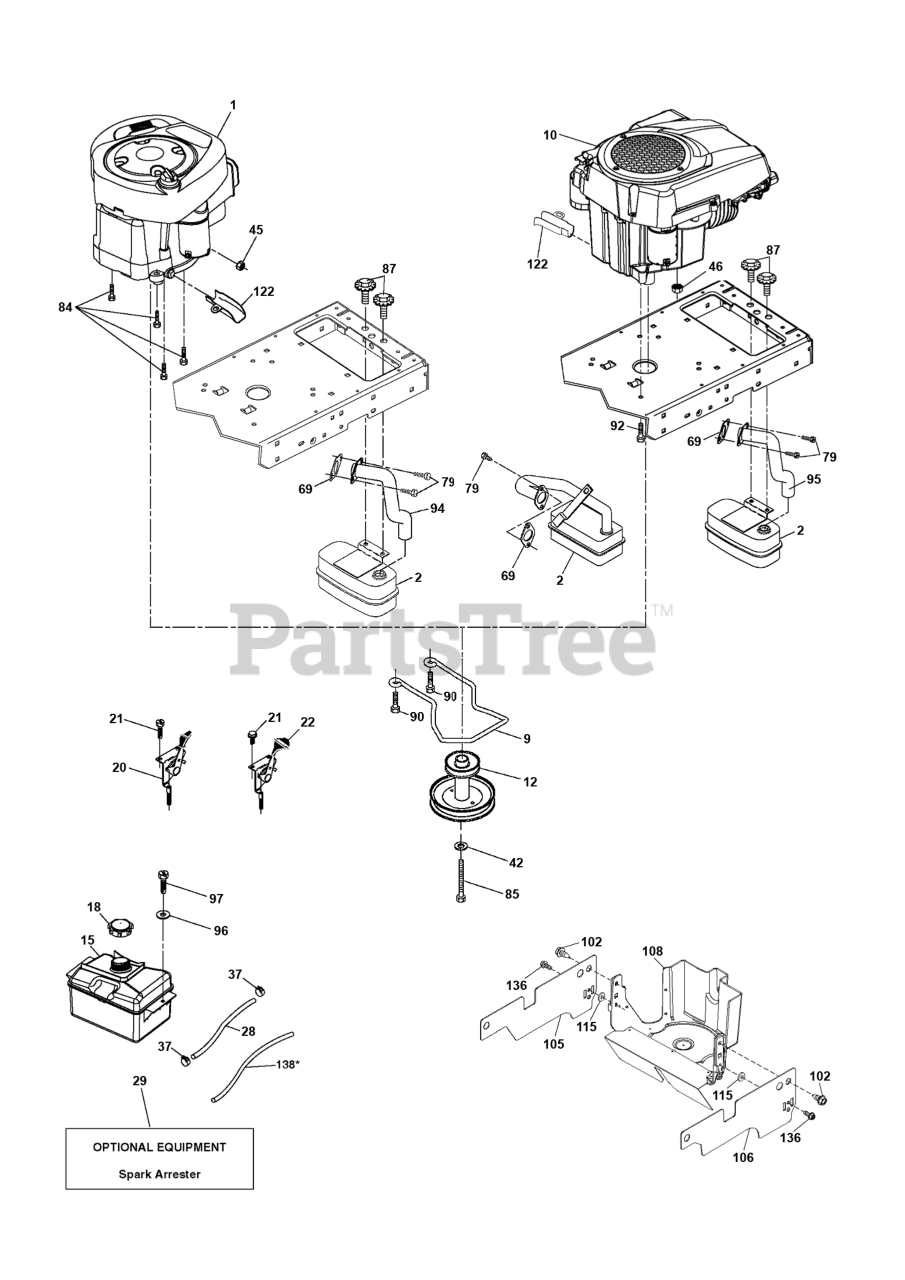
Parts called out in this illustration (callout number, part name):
2	MUFFLER.SINGLE.CYL.KOHL/B&S
2	MUFFLER.ASM.SINGLE
2	MUFFLER.LT.BRIGGS.14HP.IC/OHV
9	KEEPER.BELT.ENG.3.25"2BOLT.PNT
9	Keepers
9	KEEPER.BELT.ENG.4.25"2.BLT.431
10	ENGINE.LONCIN.SPARE/452
12	PULLEY.ENGINE
12	ENGINE.PULLEY
15	FUEL.TANK.ASM.NON-EPA
15	Tanks
18	CAP ASM.FUEL.2.25"FR.
20	THROTTLE.COBRA.21".RSTART.BLK
21	Screws
21	SCREW.#10 X 0.750.BOS
22	CONTROL.TH/CK.C.
28	HOSE.1/4".LOW.PERM.FUEL.LN.22"
28	HOSE 1/4" LOW PERMEATION FUEL
29	KIT.SPARK ARRESTOR 794945 B&S
37	HOSE CLAMP
42	Washers
42	WASHER 7/16 LOCK
45	NUT HEX_LRG FLG_1_4-20_LOCK
45	Hardware
46	NUT HEXAGON WITH FLANGE, SERRA
69	GASKET GASKET.EXHAUST.LONCIN 3
69	REPL BY 532 27 22-93
69	GASKET.EXHAUST.KOHLER
79	Screws
84	SCREW.3/8-16
85	BOLT.HEX.7/16-20X4.GR5.1.5BLUE
87	BOLT.5/16-18UNCX3/4 W/SEMS.BLK
90	SCREW 3/8-16X1
92	SCREW 3/8-16X1
94	EXHAUST.TUBE.B&S.28/31
95	TUBE TUBE.EXHAUST.LONCIN 452.T
96	WASHER
96	Washers
97	SCREW HEXWSHR 1/4-20X3/4
102	SCREW
105	SHIELD.SIDE.LH.3842"TEX FRN.BK
106	SHIELD.SIDE.LH.3842"TEX FRN.BK
108	COVER ENGINE PULLEY COVER WITH
115	RETAINER
122	EXTENSION DRAIN OIL
136	Screws
136	SCREW.#10 X 0.500
